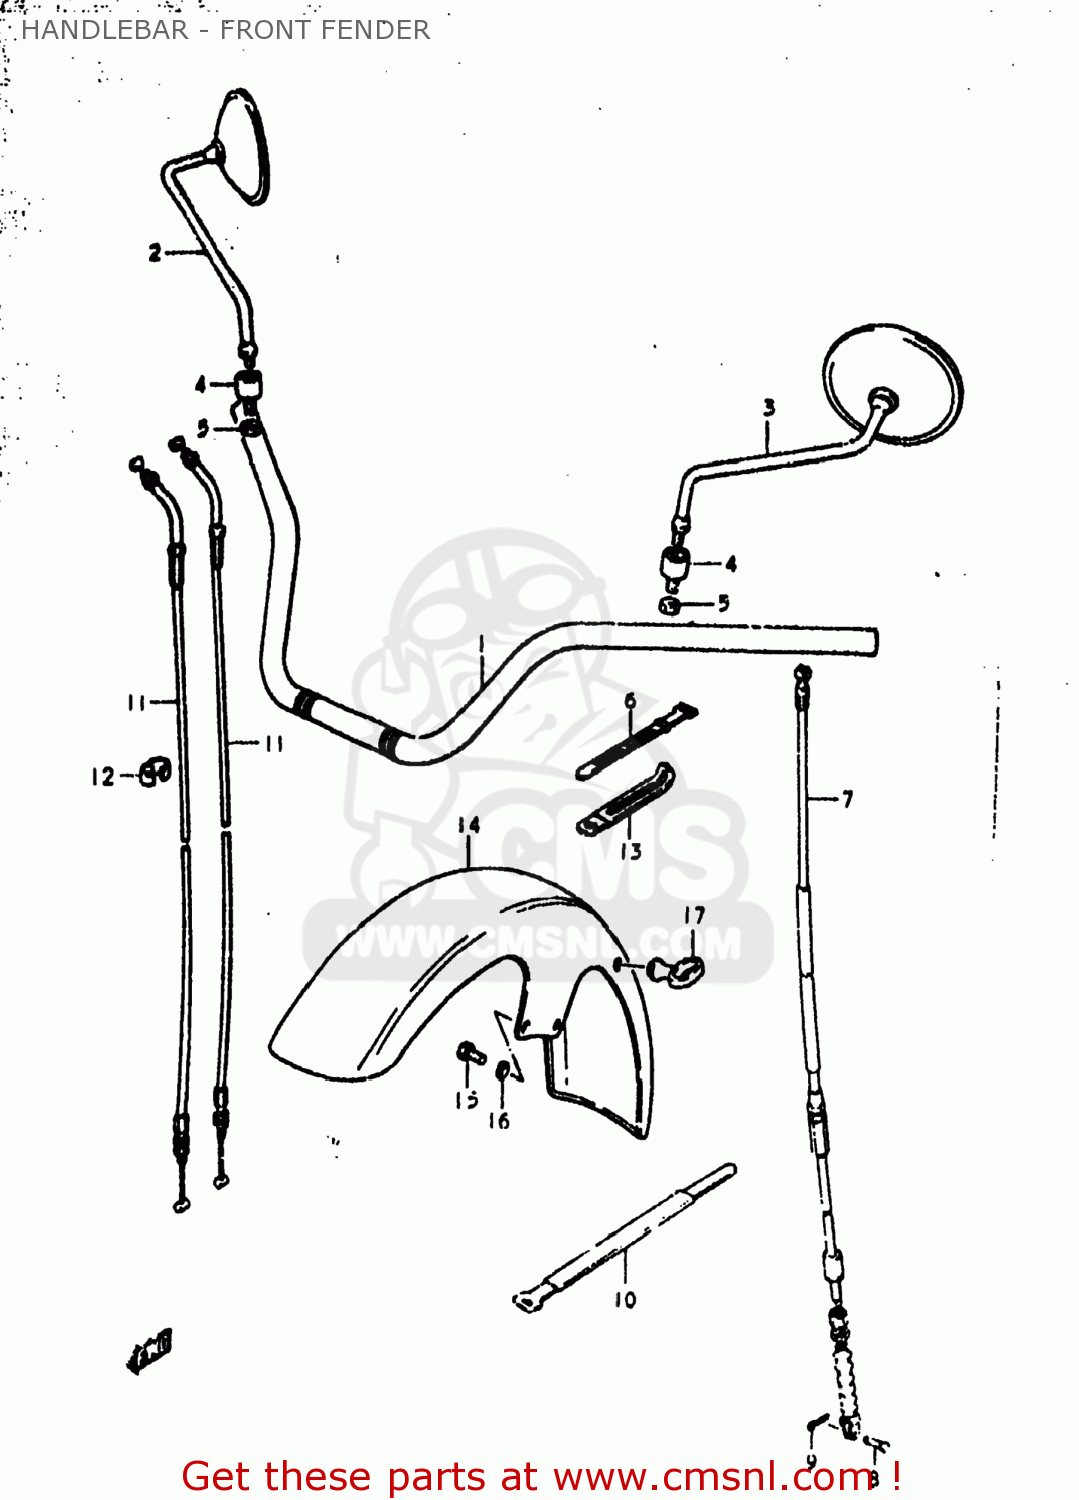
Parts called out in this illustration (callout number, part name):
1	HANDLEBAR
2	MIRROR ASSEMBLY,RIGHT
3	MIRROR ASSEMBLY,LEFT
4	CUSHION,REAR VIEW MIRROR
5	NUT
6	CLAMP(L:120)
7	CABLE ASSY,CLUTCH
8	PIN(L:15)
9	PIN
10	CLAMP
11	CABLE ASSY,THROTTLE
12	CLIP
13	CLAMP
14	FENDER,FR
15	BOLT
16	LOCK WASHER
17	GUIDE,CABLE
